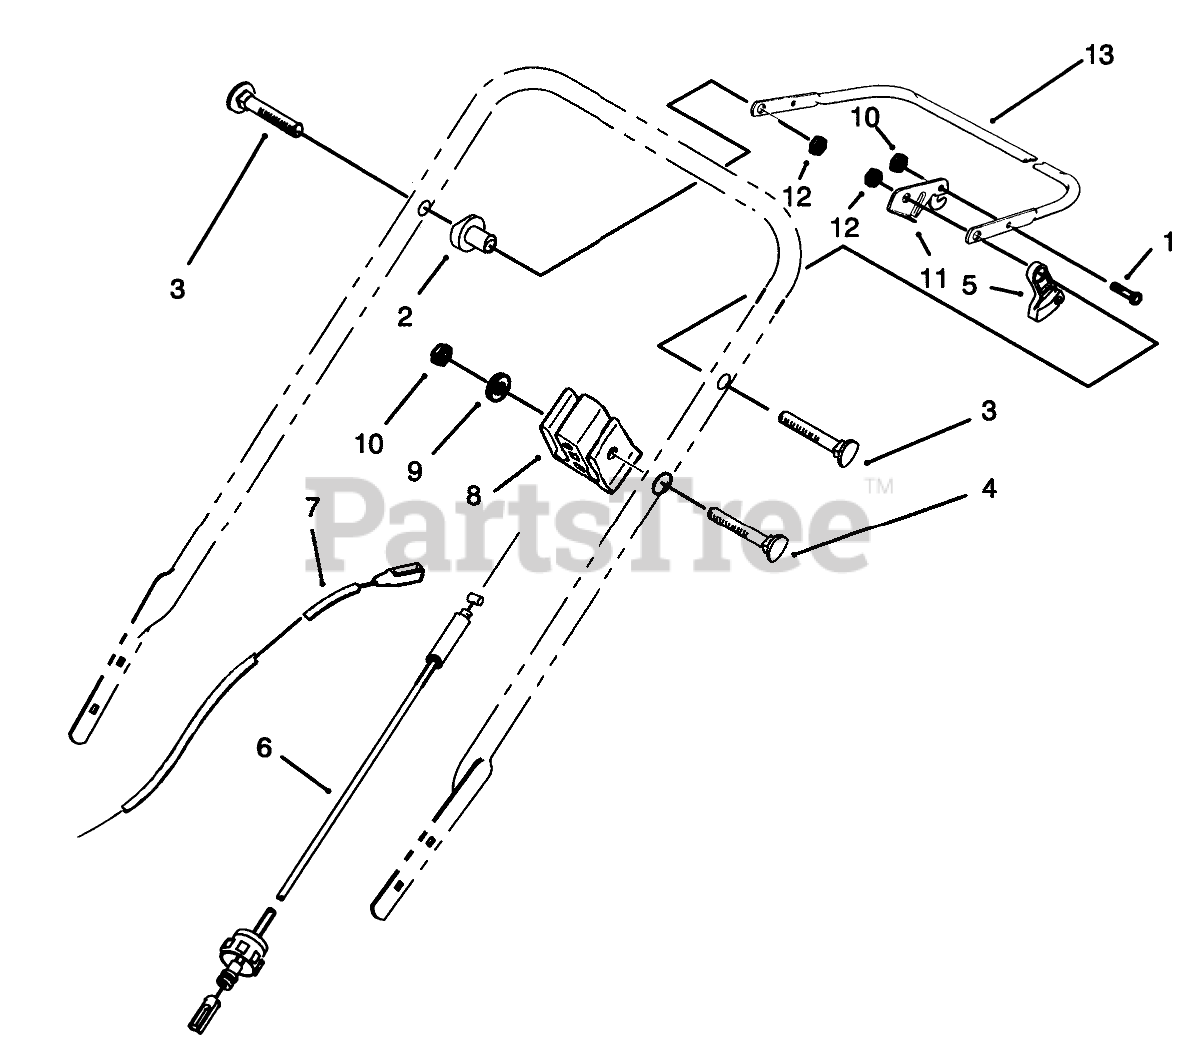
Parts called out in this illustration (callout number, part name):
1	SCREW-HH
2	SPACER-SUPPORT
3	SCREW-HANDLE
4	SCREW-HANDLE
5	LEVER-TRACTION
6	CABLE-TRACTION
7	BRAKE CONTROL
8	SUPPORT-CABLE
9	WASHER-FLAT
10	NUT-LOCK, NI
11	Lever-Control
12	NUT-LOCK NI
13	Bar-Control
